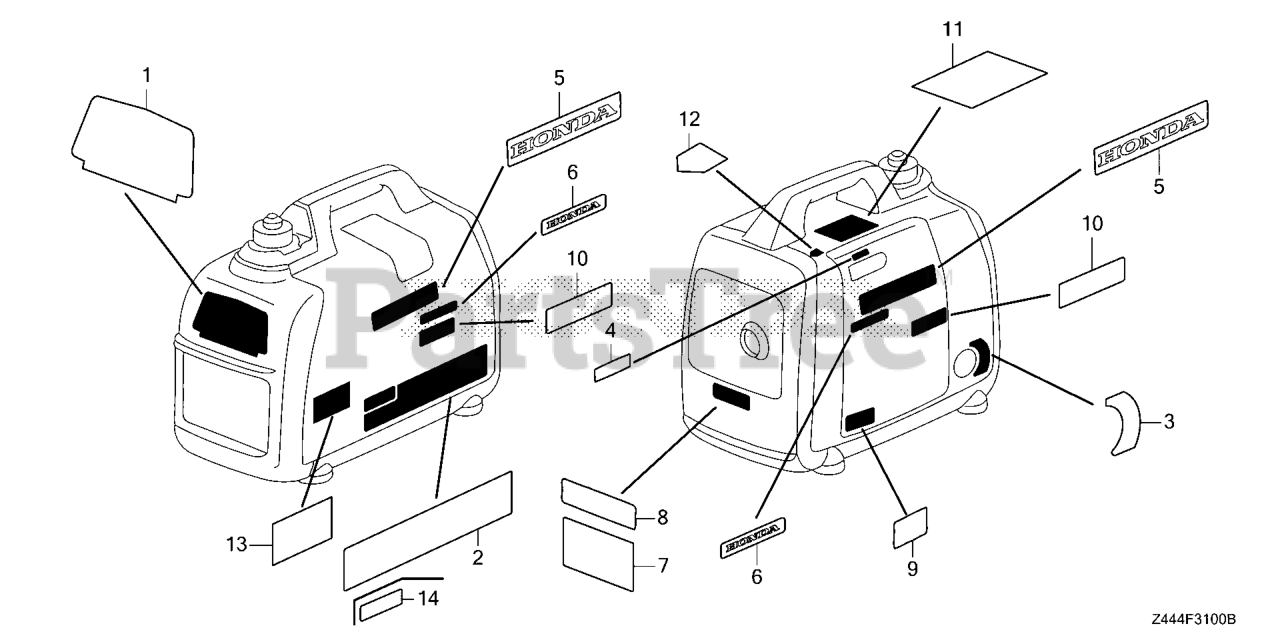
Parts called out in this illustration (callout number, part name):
1	MARK, EMBLEM
2	MARK, CAUTION
3	MARK, ENGINE SWITCH
4	MARK, CHOKE
5	MARK, HONDA
7	MARK, EX. WARNING (E)
9	MARK, OIL CAUTION
11	MARK, CPSC (CO CAUTION)
